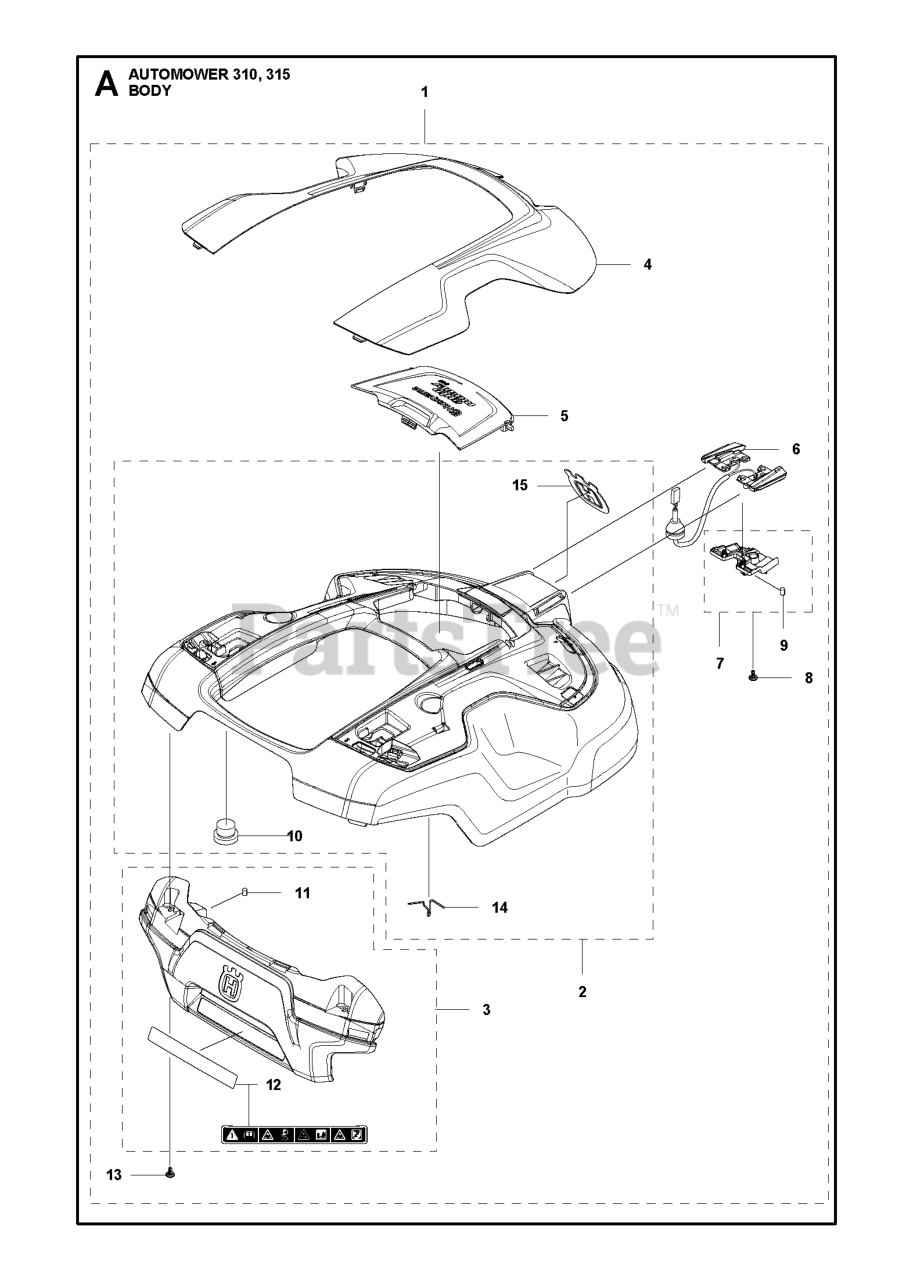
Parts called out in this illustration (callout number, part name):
1	BODY SYSTEM P15 315
1	BODY SYSTEM P15 310
3	BUMPER KIT
4	GREY COVER
4	ORANGE COVER
4	WHITE COVER
6	LOOM CHARGING PLATE
7	HOLDER KIT
8	SCREW ITXPANT
9	MAGNET NEODYMIUM D5X8
10	CAP SNAPLOC
11	MAGNET NEODYMIUM D5X8
12	LABEL WARNING P15
13	SCREW ITXPANT
14	SPRING HOOD
15	DECAL HUSQVARNA CROWN HEIGHT 5
